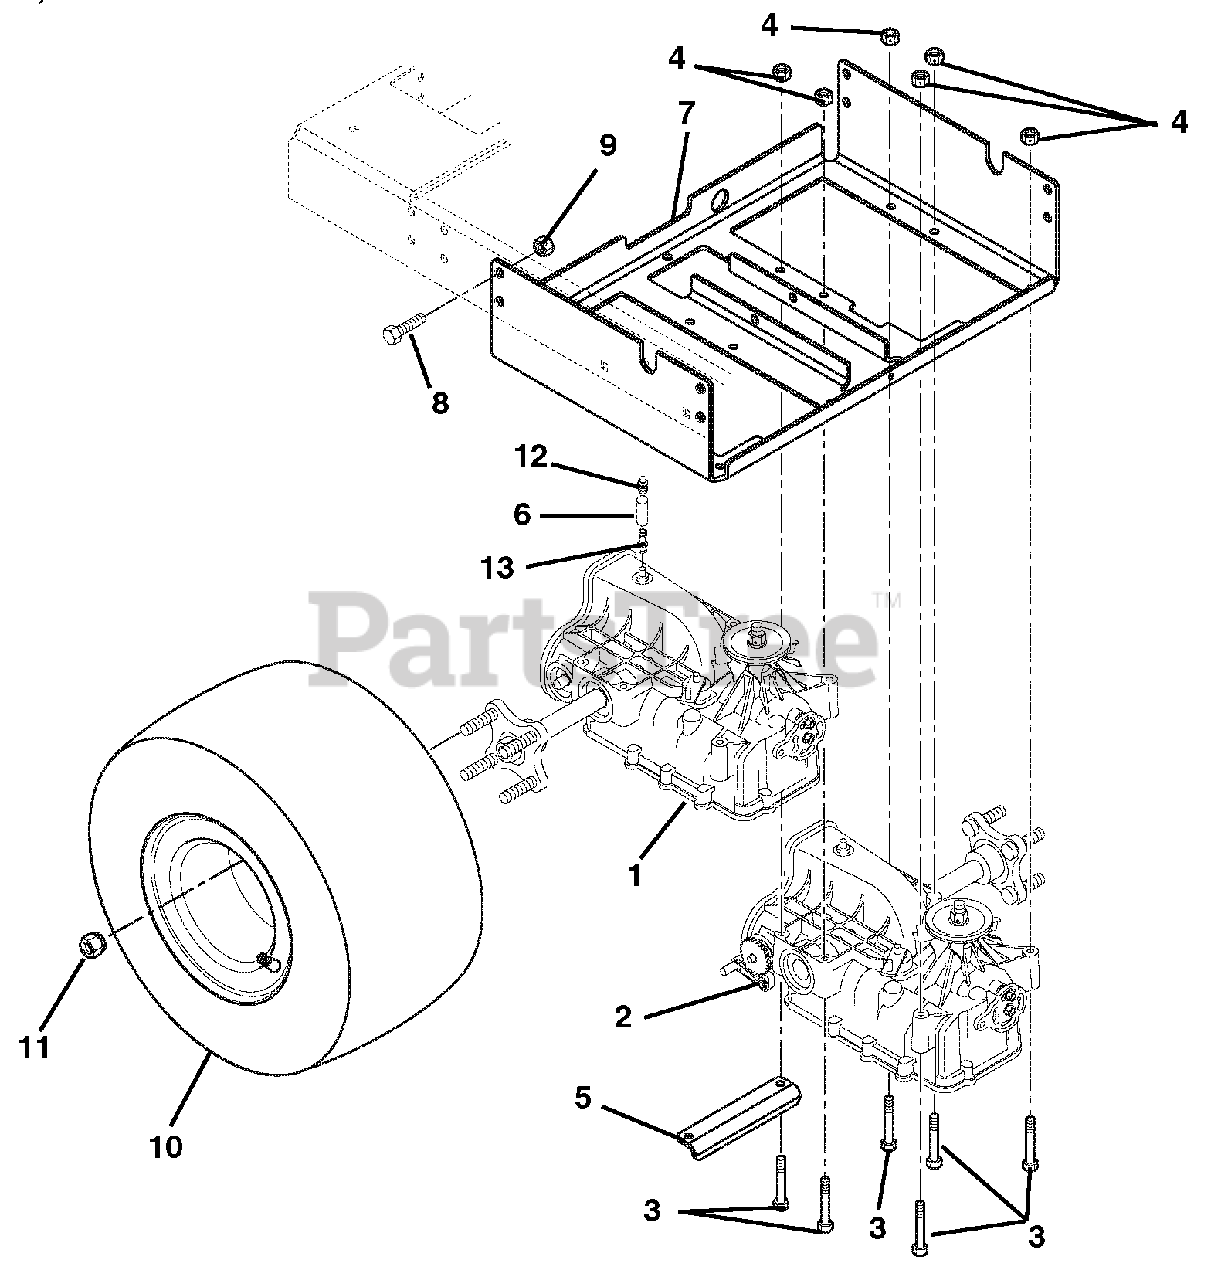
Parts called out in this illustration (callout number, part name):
1	Transaxle Hydro-Gear Right Hand (S/N 001000 & up)
1	Transaxle Hydro-Gear Right Hand (S/N 000101 - 000999)
2	Transaxle Hydro-Gear Left Hand (S/N 001000 & up)
2	Transaxle Hydro-Gear Left Hand (S/N 000101 - 000999)
3	Bolt-Hex .31-18 x 2.50 Grade 5
4	Nut-Locking-Top-Flange .31-18
5	Transaxle Bracket
6	Hose-Vent
7	Transmission Cradle
8	Bolt Serrated Hex Flange Washer Head .31-18 x .62 Grade 5
9	Nut-Locking-Top-Flange .38-16
10	Tire/Wheel 18 x 8.50-8
10	Rim for 18 x 8.50-8 Tire
10	Tire 18 x 8.50-8
11	Nut-Lug .50-20
12	Cap-Vent 1/2" Hydro-Gear
13	Fitting-Straight 1/2" O-Ring Hydro-Gear
